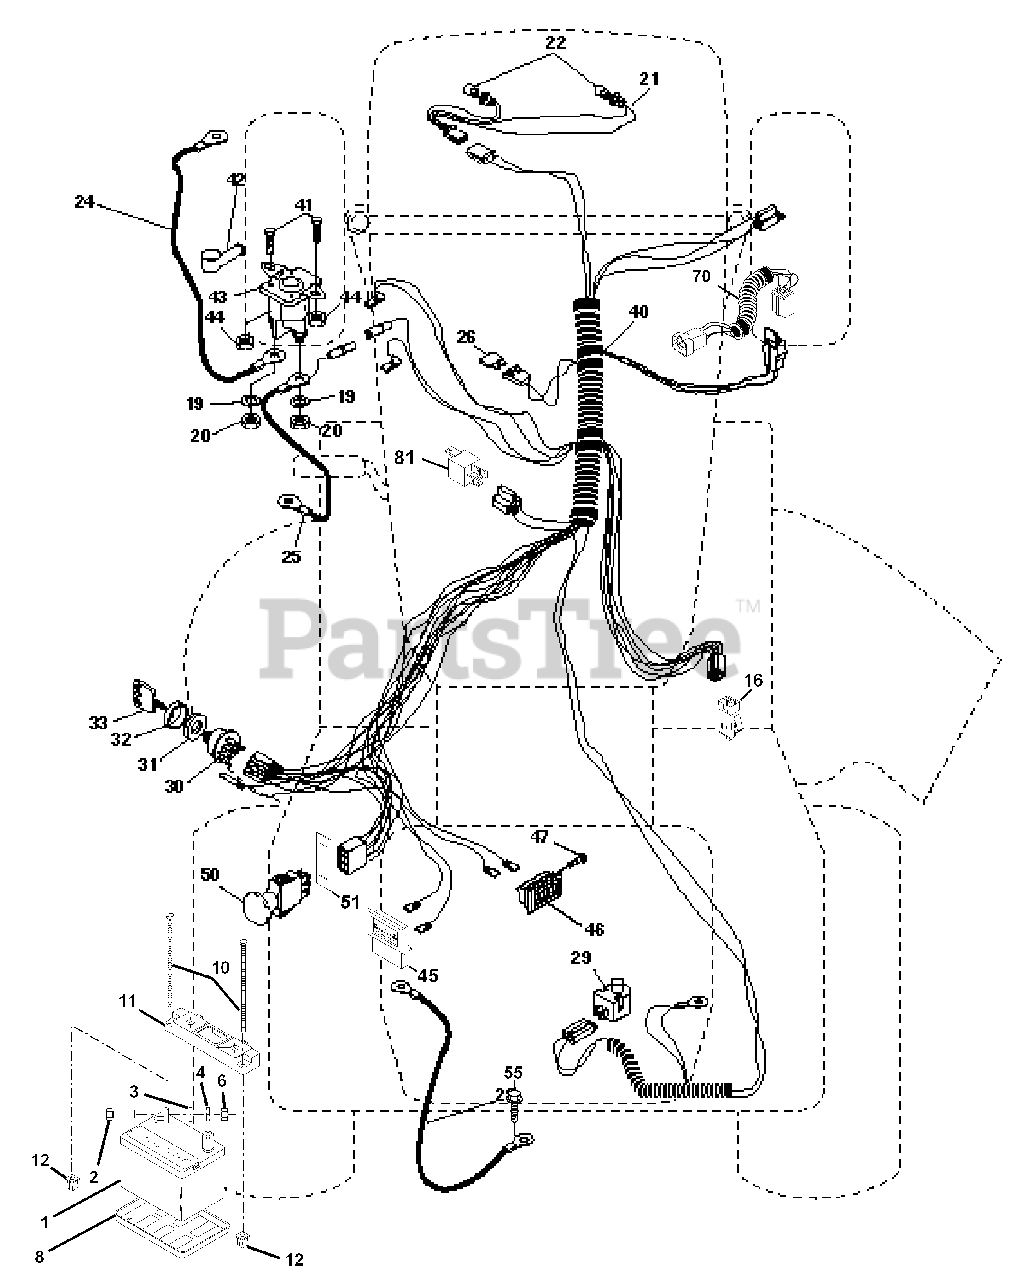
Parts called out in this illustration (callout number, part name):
1	Battery 12 Volt 35 AMP
2	Bolt Hex Hd 1/4-20unc X 3/4
3	Washer 9/32 X 5/8 X 16 Ga.
4	Washer Lock Hvy Helical 1/4
6	Nut Fin Hex 1/4-20 Unc
8	Case Battery Mech Hinge
10	Bolt Brt Frt 1/4-20 x 75 Ainc
11	Holddown Battery Front Mount
12	Nut Push Nylon 1/4" Battery Frt
16	Switch Interlock Push-In
19	Washer Lock 1/4
20	Nut Jam Hex 1/4-20 Unc
21	Harness Asm Light W/4152j
22	Bulb Light #1156
24	Cable Battery 6 Ga 11" red
25	Cable Battery 6 Ga 22" red w/16 wire
26	Fuse 30 AMP Auto Green
28	Cable Ground 6 Ga 21" black
29	Switch Plunger Nc Gray
30	Switch Ign 4 pos w/lights
31	Nut Ignition
32	Cover Sw Ignition
33	Key Ign Modelled Generic
40	Harness Ign.
41	Bolt Blk Fin Hex 1/4 - 20 x 1/2
42	Cover Terminal Red
43	Solenoid
44	Nut Keps Hex 1/4-20 Unc
45	Ammeter Rectangular 15 Amp
46	Meter Hour
47	Screw 10-24 x 1/2 Black
50	Switch PTO 3 PDT Black Delta 96
51	Ring Retainer TTO
55	Screw Thdrol 5/16-18 x 1-1/2 Tyt
70	Harness, Eng.
81	Relay Asm.
